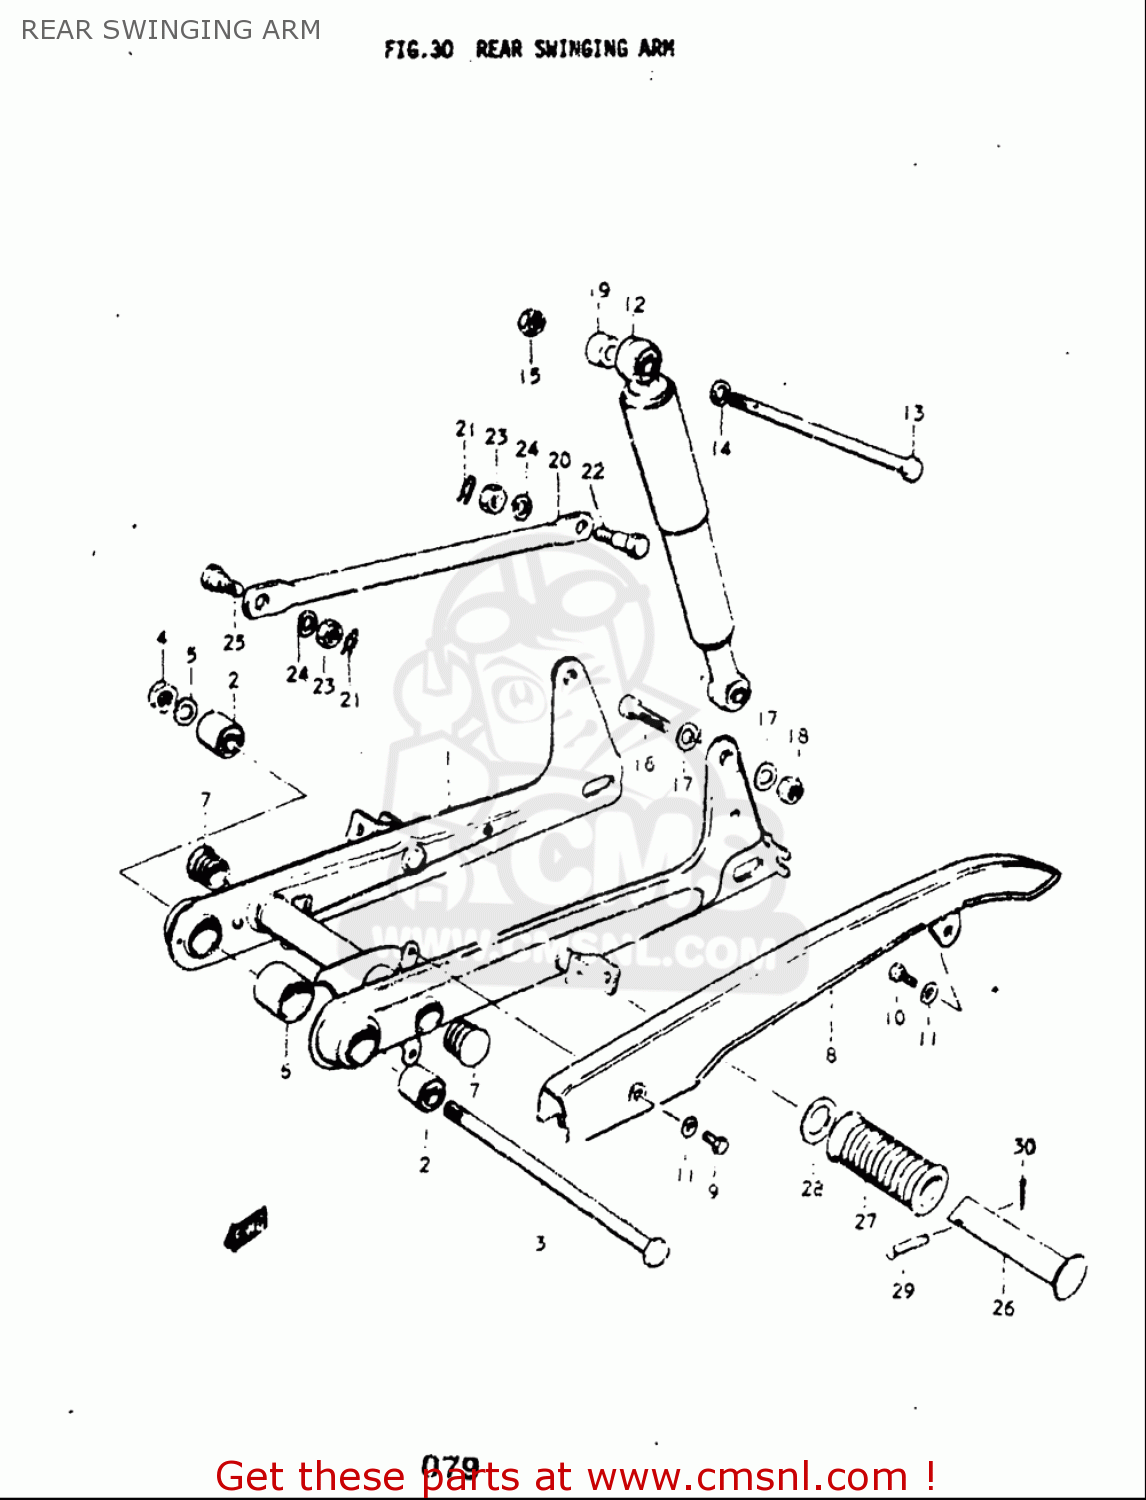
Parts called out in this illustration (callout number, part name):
2	BUSHING(10X23X35)
3	SHAFT,RR SWINGINGARM PIVOT
4	NUT
5	WASHER,LOCK
6	CUSHION
7	CAP(OD:26)
10	BOLT(6X14)
11	WASHER
12	ABSORBER ASSY,RR SHOCK
13	SHAFT,RR SHOCK ABSORBER UPR
14	WASHER
15	NUT
16	BOLT(10X43)
17	WASHER
18	NUT
21	CLIP
22	BOLT(8X26.5)
23	NUT
24	WASHER,LOCK
25	BOLT(8X22.5)
26	BAR,FOOTREST RUBBER
27	RUBBER,PILLION FOOTREST
28	WASHER(19.5X32X2)
29	PIN
30	PIN
